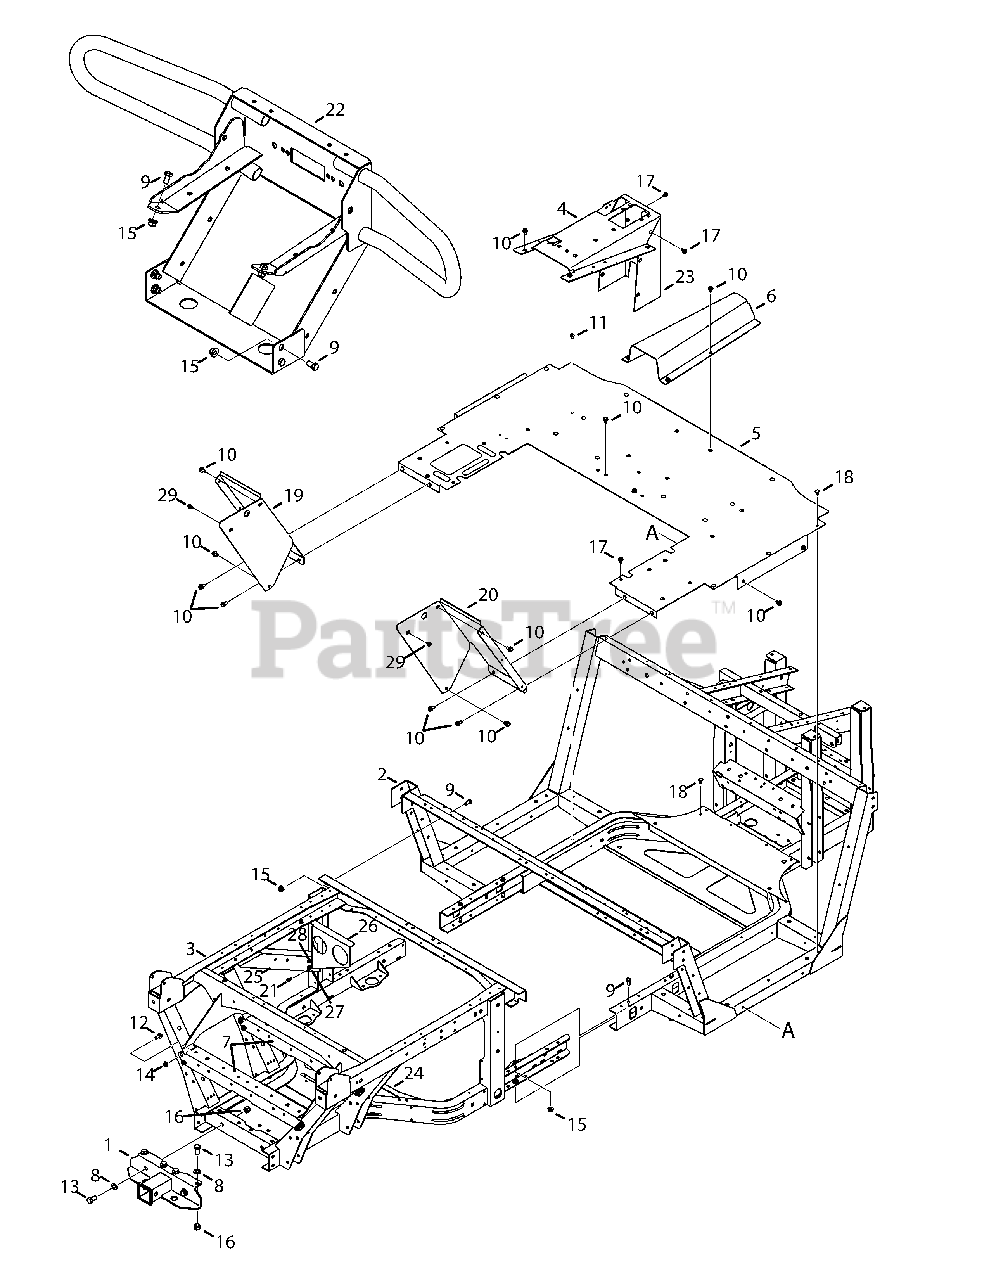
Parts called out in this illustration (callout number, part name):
1	Hitch Assembly, receiver Rr
2	Frame Assembly, front, uv
3	Frame Assembly, rear, uv
4	Plate, console, 4x4, top
6	Cover, front, 4x4
7	Channel, support, rear
8	Washer, Flat, .510 x 1.00 x .060
9	Screw, 3/8-16 x .75, gr5, std
10	Screw, tt, 5/16-18 x 0.750
11	Screw, ab, 1/4-14, 0.625
12	Screw, Hxflg, 5/16-18 (4x4)
13	Screw, 1/2-13, 1.25, gr5, std
14	Nut, Flange Lock, 5/16-18, Nylon
15	Nut, Flange Lock, 3/8-16, Nylon
16	Nut, Hex Lock, 1/2-13, Nylon
17	Screw, tt, 5/16-18 x 0.500
18	Clip, Panel, ret,
19	Bracket, Lh, Shield
20	Bracket, Rh, Shield
21	Screw, tt, 1/4-20 x .500
22	Bumper Assembly, front
23	Plate, console, 4x4, front
24	Bracket Assembly, ISO, Trans/ Eng
25	Bracket Assembly, Air Filter Mnt
26	Bracket Assembly, Supt, Hose
27	Hex Head Screw, 1/4-20 x .620
28	Nut, Flange Lock, 1/4-20
29	Screw, tt, 1/4-20x.625, hxindwsh
